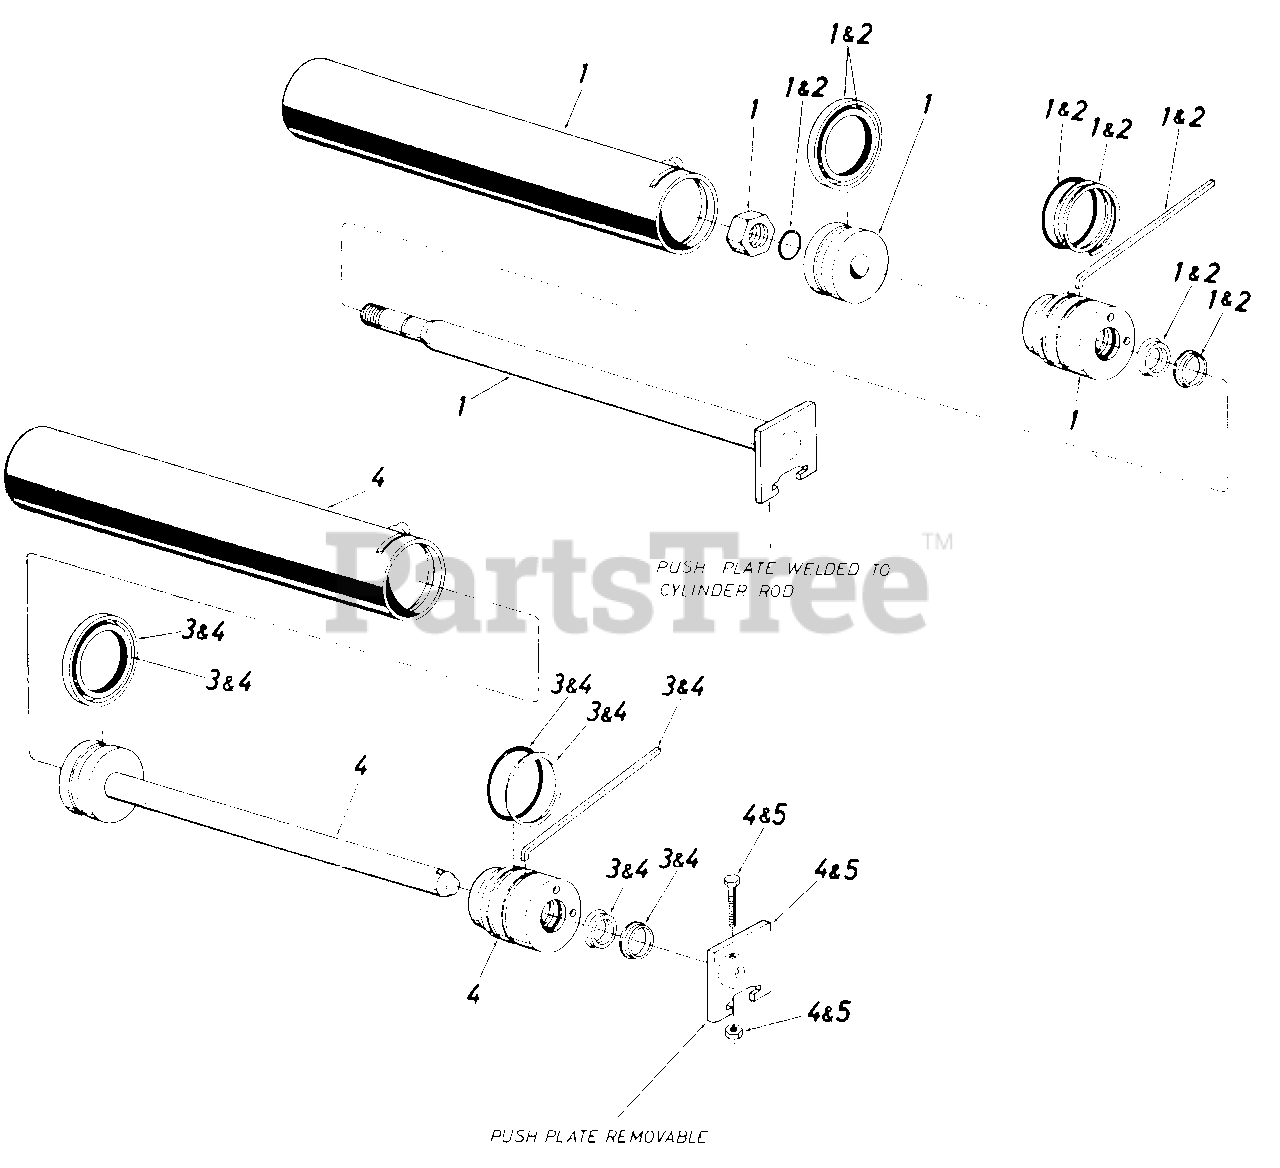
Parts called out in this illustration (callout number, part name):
1	Cylinder Ass'y. Comp.
2	3-1/2" Cyl. Kit "O"-Ring Set
3	3-1/2" Cyl. Kit "O"-Ring Set
4	Cylinder Ass'y. Comp.
5	3-1/2" Cyl. Push Plate Kit
